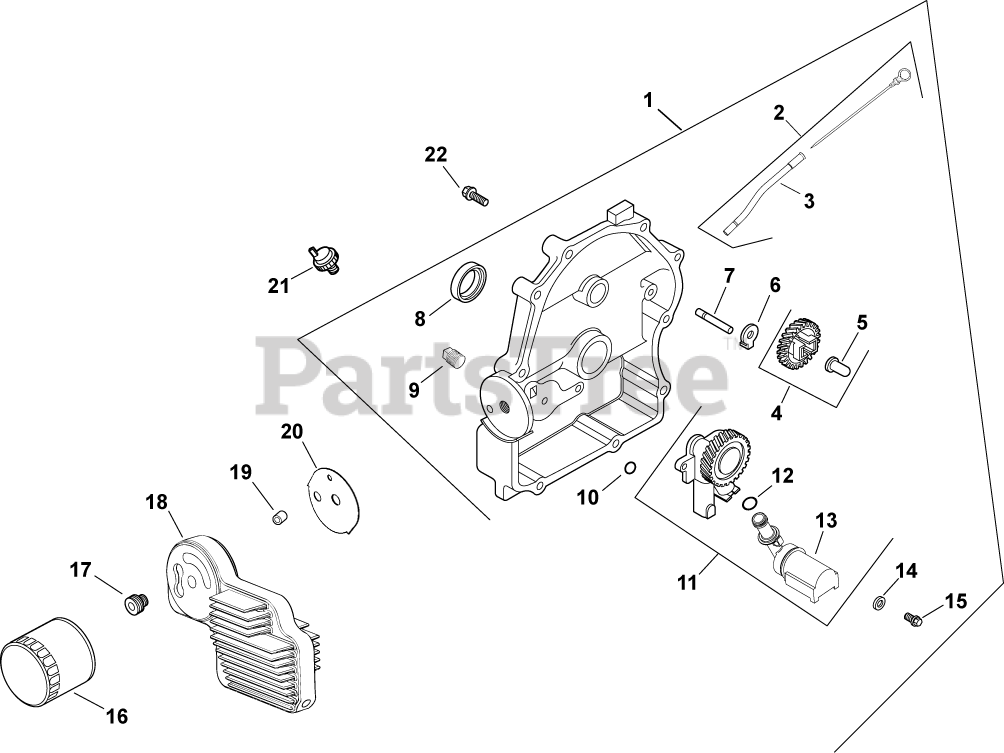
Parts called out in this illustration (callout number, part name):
1	CLOSURE PLATE ASSEMBLY USE 24 009 237-S
2	KIT, DIPSTICK/DIPSTICK TUBES
4	KIT, GOVERNOR GEAR W/PIN
5	PIN, GOVERNOR REGULATING
6	TAB, LOCKING
7	SHAFT, GOVERNOR GEAR
8	SEAL, OIL
9	PLUG, CTSK PIPE 1/8"
11	PUMP ASSEMBLY, OIL-USE 24 393 53-S
12	O-RING, OIL PICK-UP
13	PICK-UP, OIL
14	WASHER, FLAT 6 MM
15	SCREW,FLG THD FRM M6X1.0X25-(#25086395S)
16	OIL FILTER
17	NIPPLE, OIL FILTER
18	COOLER, OIL ASSEMBLY
19	PIN, LOCATING
20	GASKET, OIL FILTER ADAPTER USE 24 041 88-S
21	SENSOR, OIL PSI
22	SCREW, FLG M8X1.25X45
